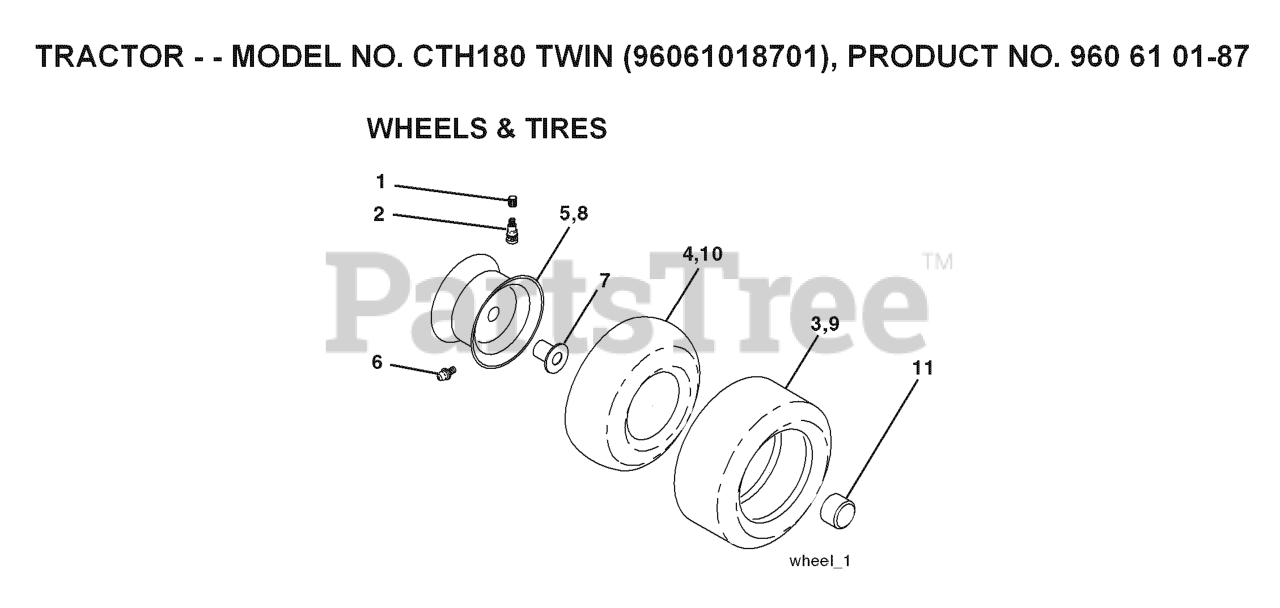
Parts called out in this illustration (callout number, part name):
2	VALVE STEM LT
3	TIRE HEAVY DUTY
4	TUBE.5.3/4.5/6
5	RIM ASM 6" FRONT SILVER
6	FITTING LT
7	BEARING T
8	RIM ASM 8" REAR SILVER
9	TIRE.TS.20X10-8
10	TUBE
11	CAP, AXLE BLK
